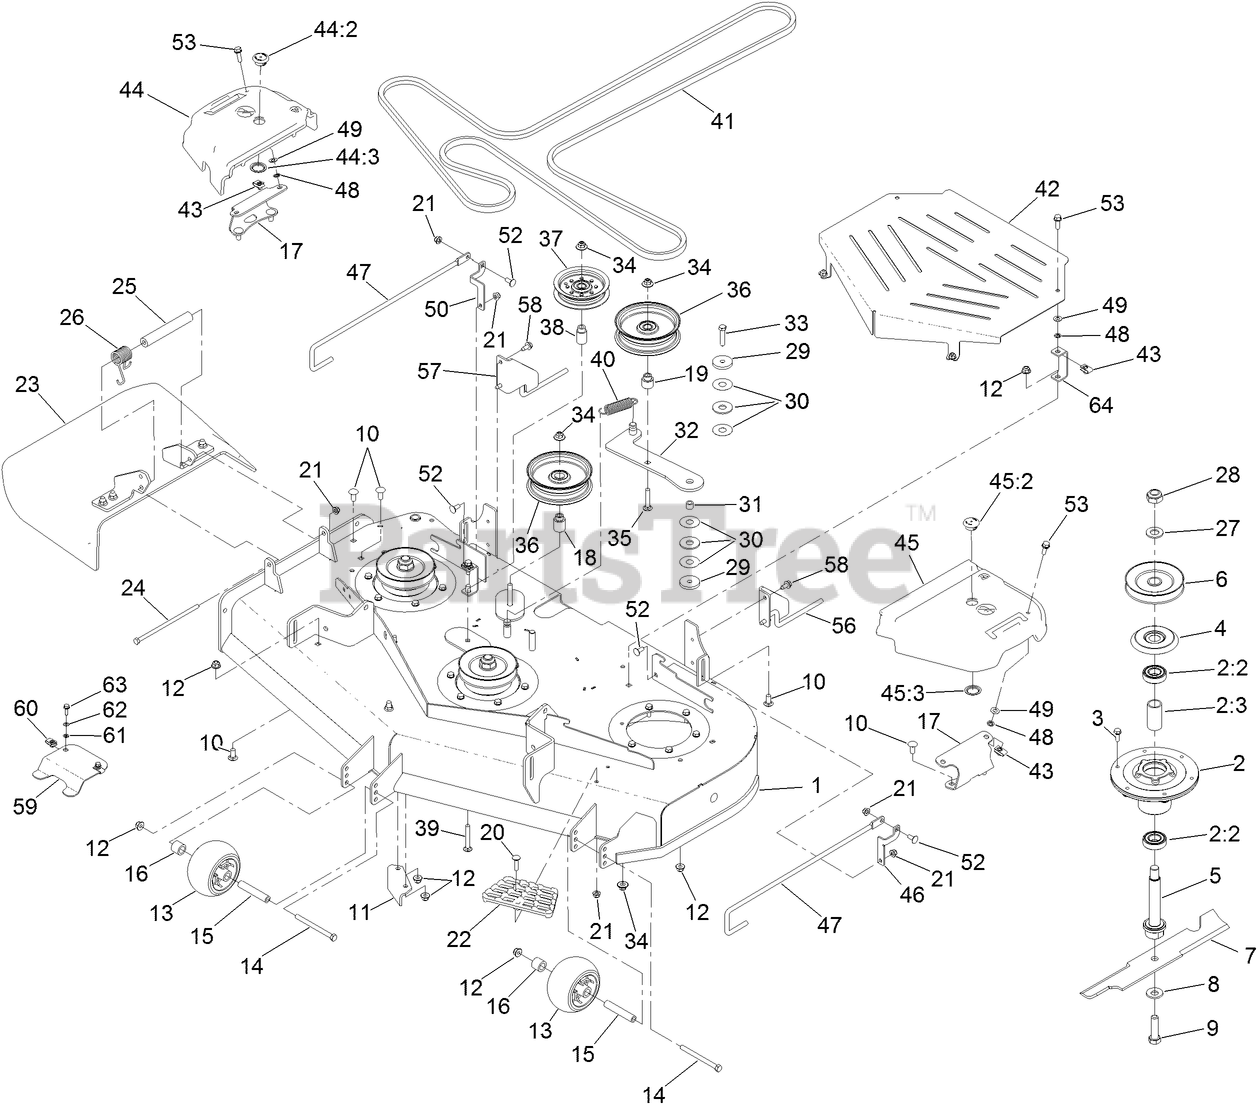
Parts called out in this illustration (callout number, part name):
1	DECK DECAL ASM
2	SPINDLE ASM
2:2	BEARING-BALL
2:3	SPACER-BEARING
3	SCREW-TAPTITE
4	SHIELD-BEARING
5	SHAFT-SPINDLE
6	PULLEY
7	BLADE-ROTARY, 16.5IN (HI FLOW)
8	WASHER-BELLEVILLE
9	SCREW-BLADE
10	SCREW-CARR
11	BAFFLE-DISCHARGE
12	NUT-HF, NI
13	ROLLER-SCALP, ANTI
14	SCREW-HH
15	TUBE-SPANNER
16	TUBE-SPACER
17	BRACKET-COVER, BELT
18	BUSHING-IDLER
19	BUSHING-IDLER
20	SCREW-CARR
21	NUT-HF, NI
22	STEP-DECK
23	DEFLECTOR ASM
24	SCREW-HH
25	SPACER
26	SPRING-TORSION
27	WASHER
28	NUT-LOCK, NI
29	WASHER-PLAIN
30	WASHER-FRICTION, COMPOSITE
31	BUSHING-LEVER, LIFT
32	ARM-IDLER
33	SCREW-HH
34	NUT-FLANGE, NI
35	SCREW-CARR
36	IDLER-PULLEY, FLAT
37	PULLEY-IDLER
38	BUSHING-IDLER
39	SCREW-CARR
40	SPRING-EXTENSION
41	BELT, DECK DRIVE
42	GUARD-CENTER BELT 48
43	NUT-U
44	RH BELT COVER ASM
44:3	RING-RETAINING
45	LH BELT COVER ASM
45:3	RING-RETAINING
46	BRACKET-MOUNT, REAR (LH)
47	ROD-SUPPORT, LOWER
48	NUT-PUSH
49	WASHER-THRUST
50	BRACKET-MOUNT, REAR (RH)
52	SCREW-CARR
53	SCREW-HHF
56	SUPPORT-LOWER, LH
57	SUPPORT-LOWER, RH
58	SCREW-HWHTF
59	PLATE-CLAMP, FOOTPAN
61	NUT-RETAINER
62	WASHER-FLAT
63	SCREW-HHF
64	BRACKET-GUARD
